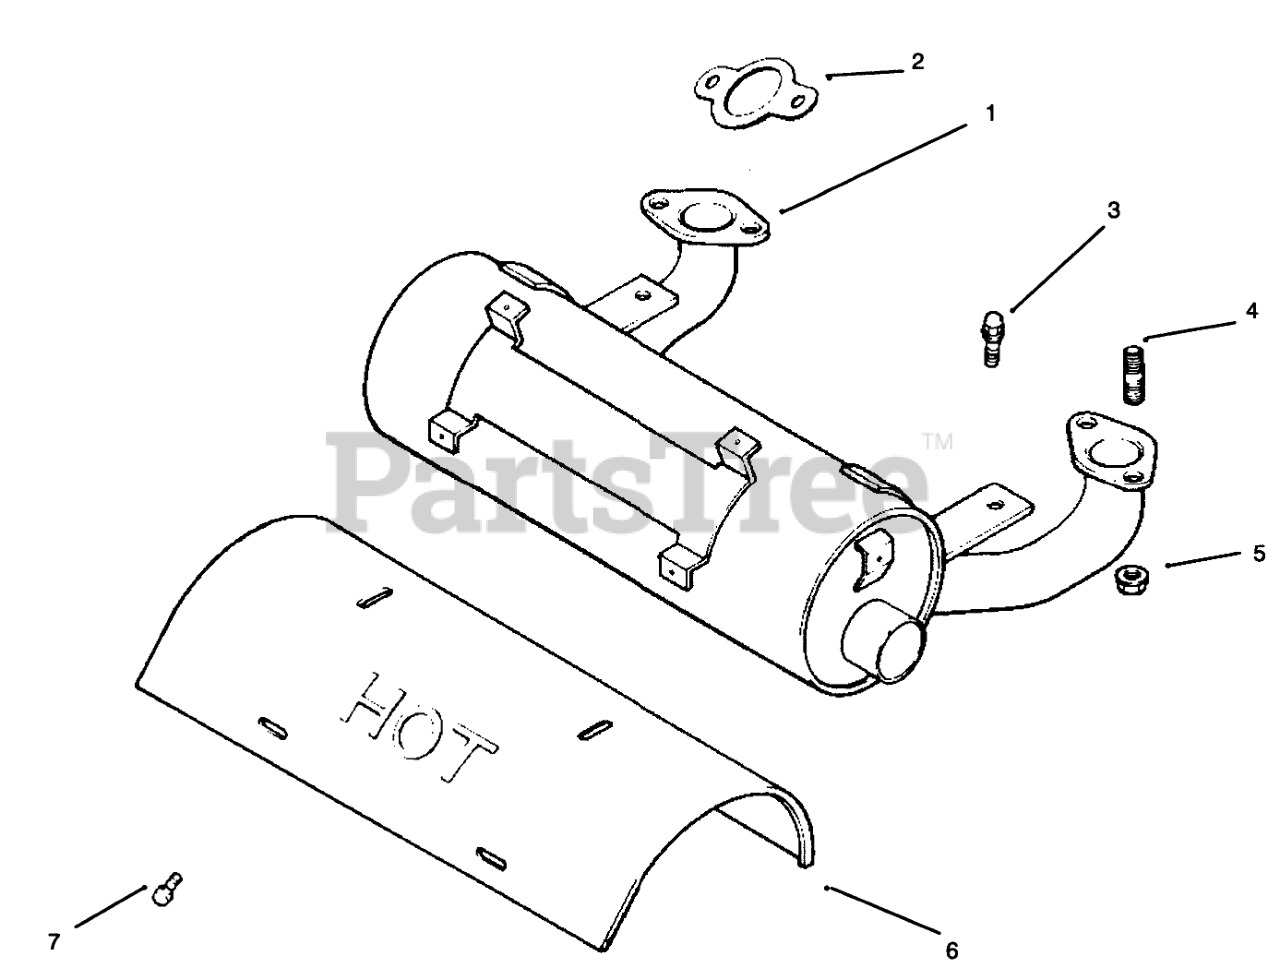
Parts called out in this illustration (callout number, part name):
1	Muffler
2	Gaskt-Exhaust
3	Screw
4	Stud
5	Nut
6	Duct-Heat Shield
7	Screw
